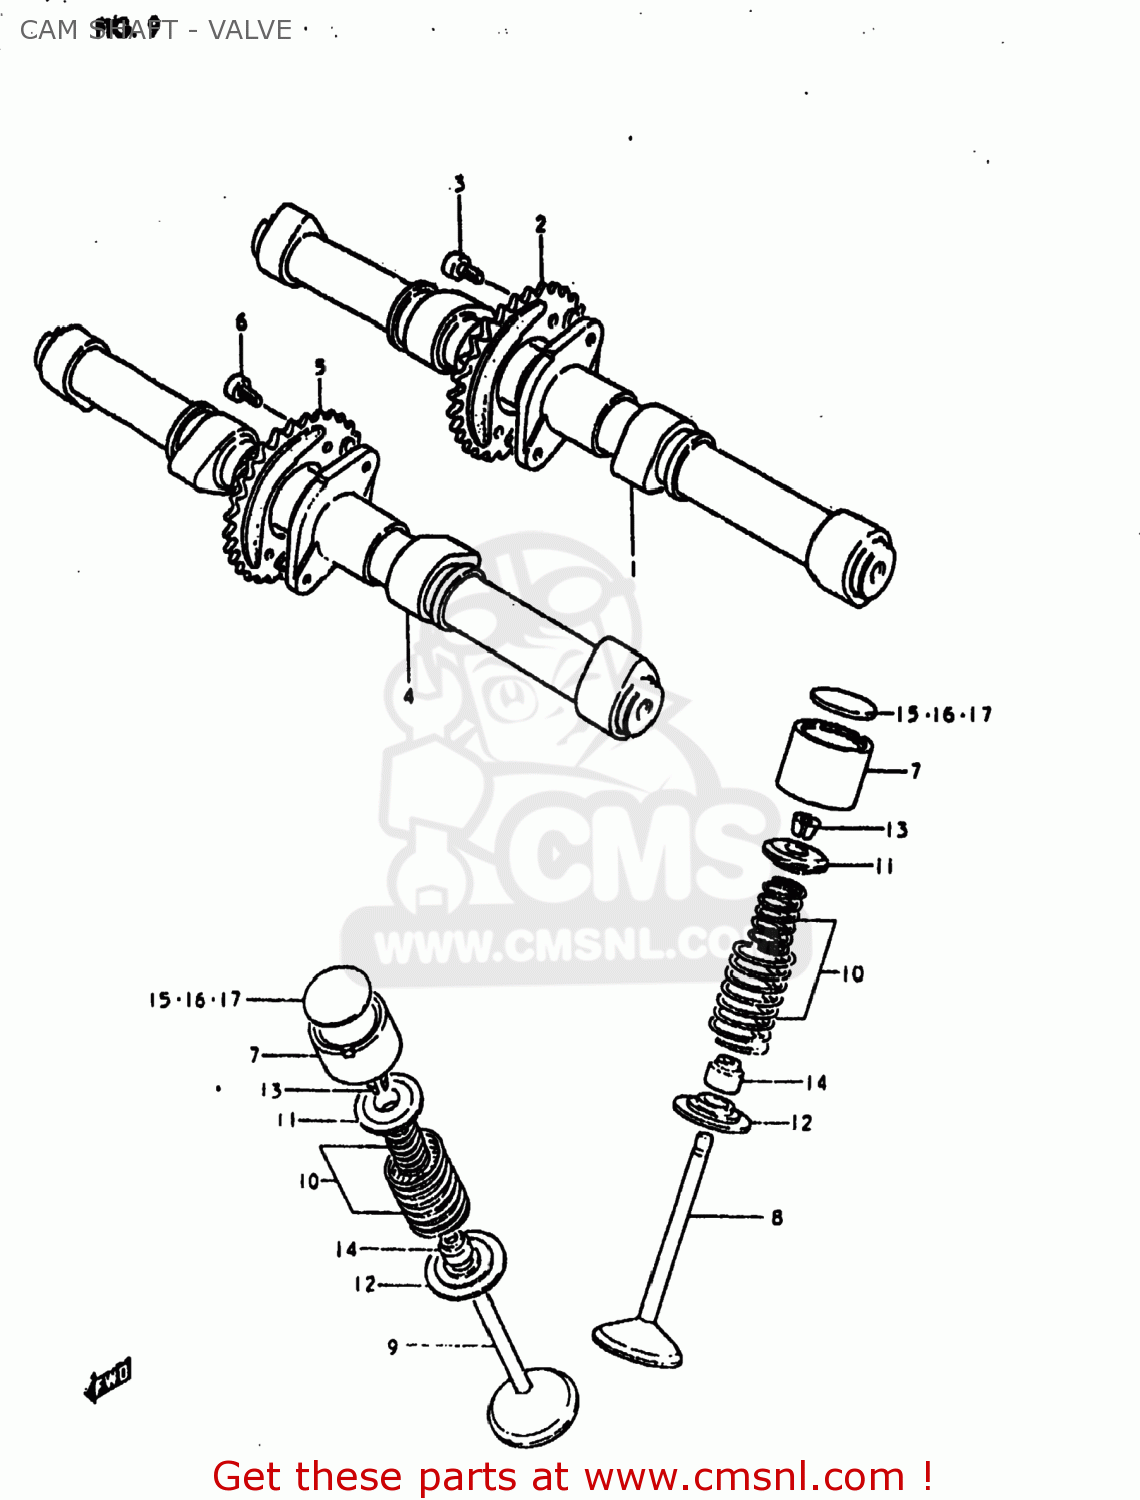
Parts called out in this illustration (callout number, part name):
1	CAMSHAFT
2	SPROCKET,INTAKE CAMSHAFT
3	BOLT 6X11
4	CAMSHAFT,EXHAUST
5	SPROCKET,EXHAUST CAMSHAFT
6	BOLT 6X11
7	TAPPET
8	VALVE,INTAKE
9	VALVE,EXHAUST
10	SPRING SET,VALVE
11	RETAINER,VALVE SPRING
12	SEAT,VALVE SPRING
13	COTTER VALVE
14	SEAL,OIL(7X14.4X9)
15	SHIM,TAPPET
16	SHIM,TAPPET
17	SHIM,TAPPET
18	SHIM SET,TAPPET
19	CASE
